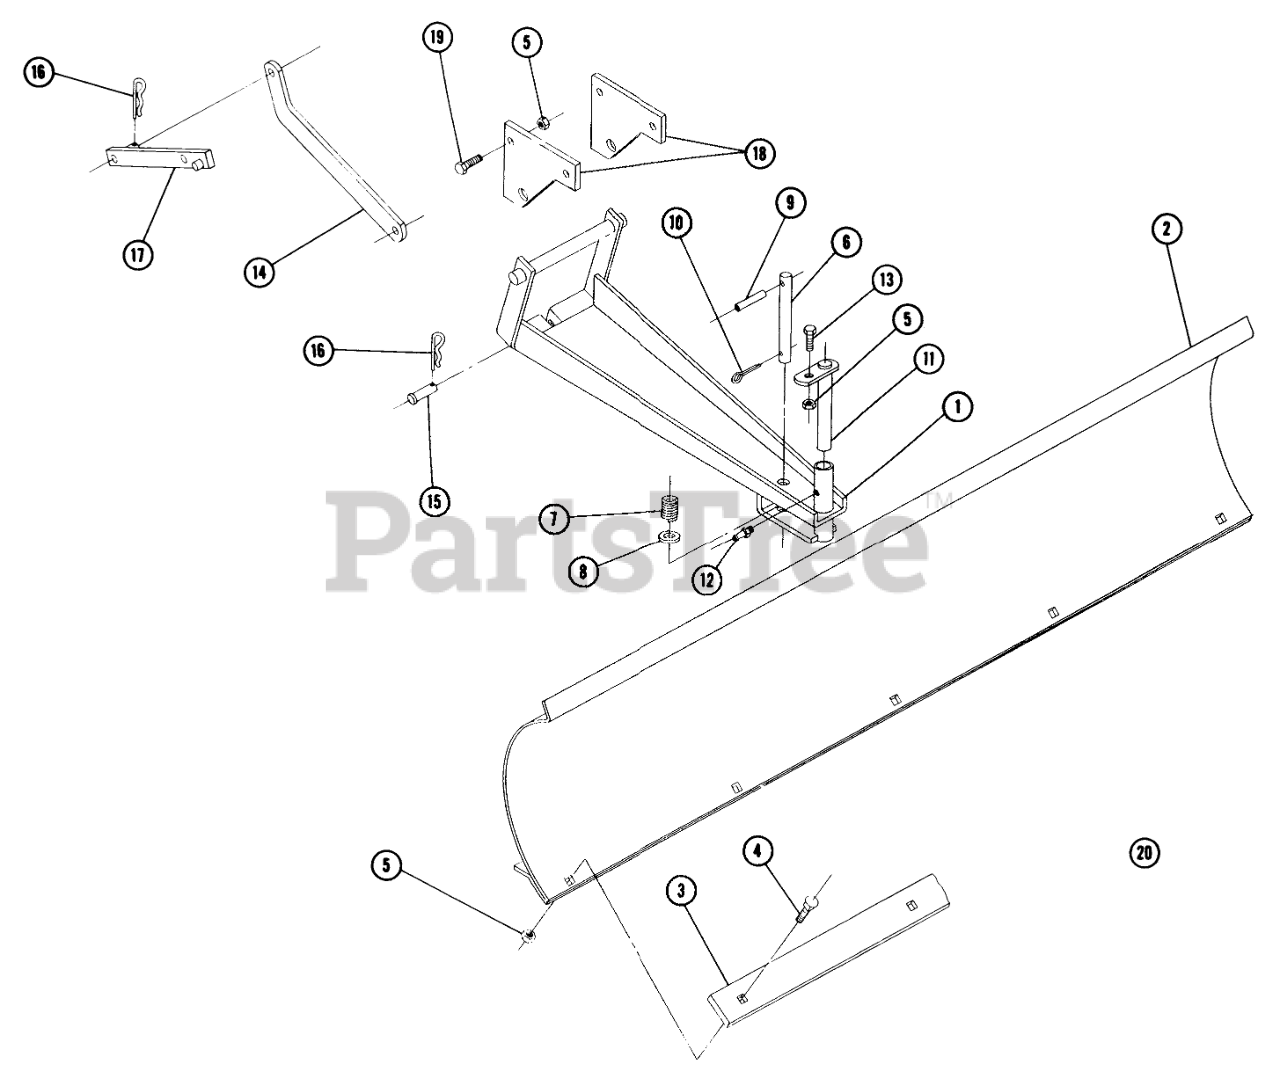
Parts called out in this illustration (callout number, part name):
1	Ass-y. Frame
2	Ass-y. Blade
3	Wear Plate
4	Bolt-3/8-16 x 3/4
5	3/8-16 E.S.
6	Pin-Pawl
7	Spring-Compression
8	Washer, 5/8
9	Roll Pin 1/4 x 2 1/2
10	Cotter Pin
11	Pivot Pin
12	Zerk
13	Bolt Hex 3/8-16 x 5/8
14	Link-Lower Lift
15	Pin Clevis
16	Hairpin
17	Ass-y. Link-Upper
18	Plate-Mtg. Bracket
19	Bolt 3/8-16 x 3/4
20	Decal
